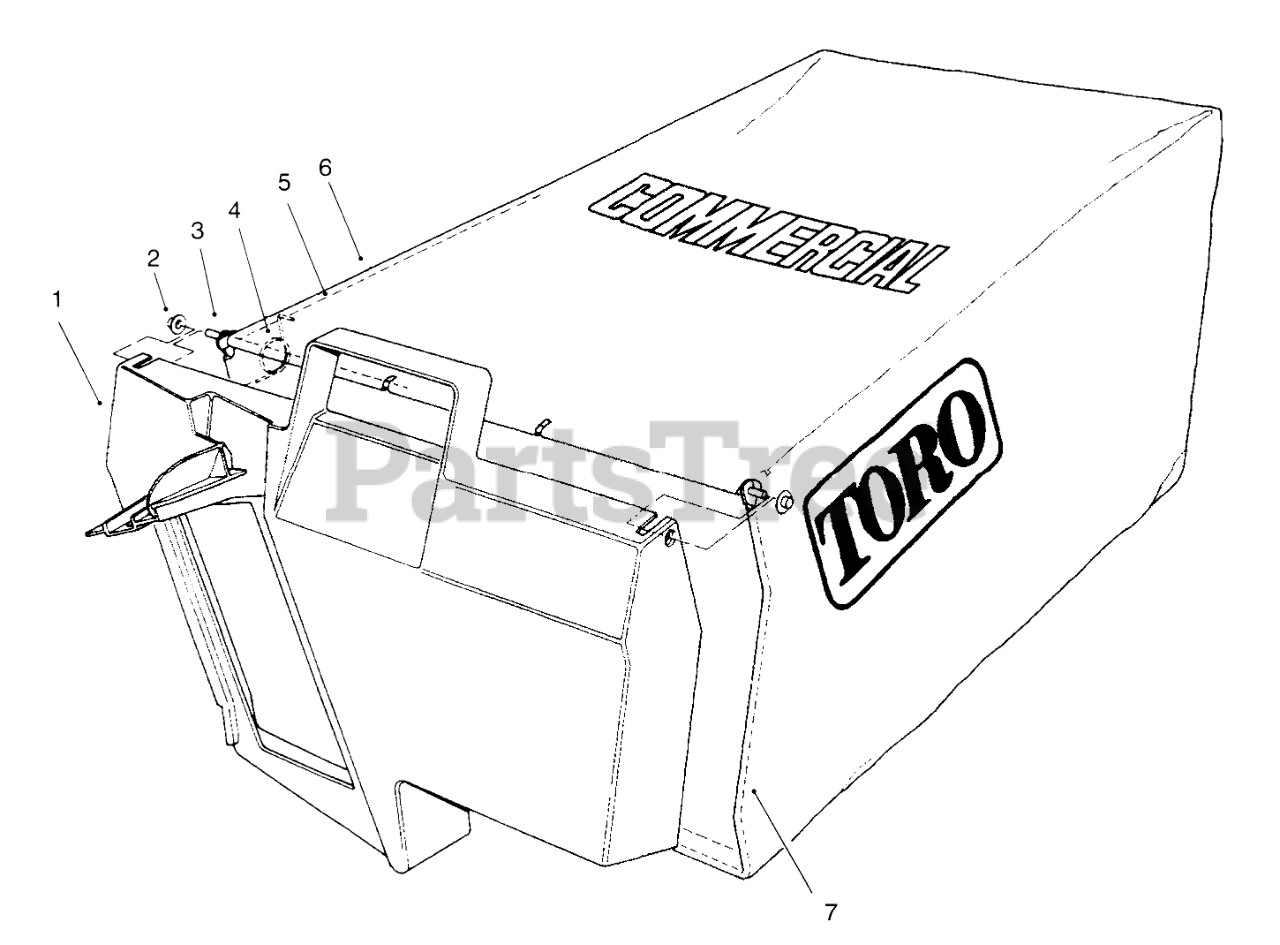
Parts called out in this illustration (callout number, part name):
1	DOOR-BAG, GRASS
2	NUT-PUSH
3	HINGE-DOOR, BAG
4	SPRING
5	FRAME-BAG, UPPER
6	Bag
7	FRAME-BAG
